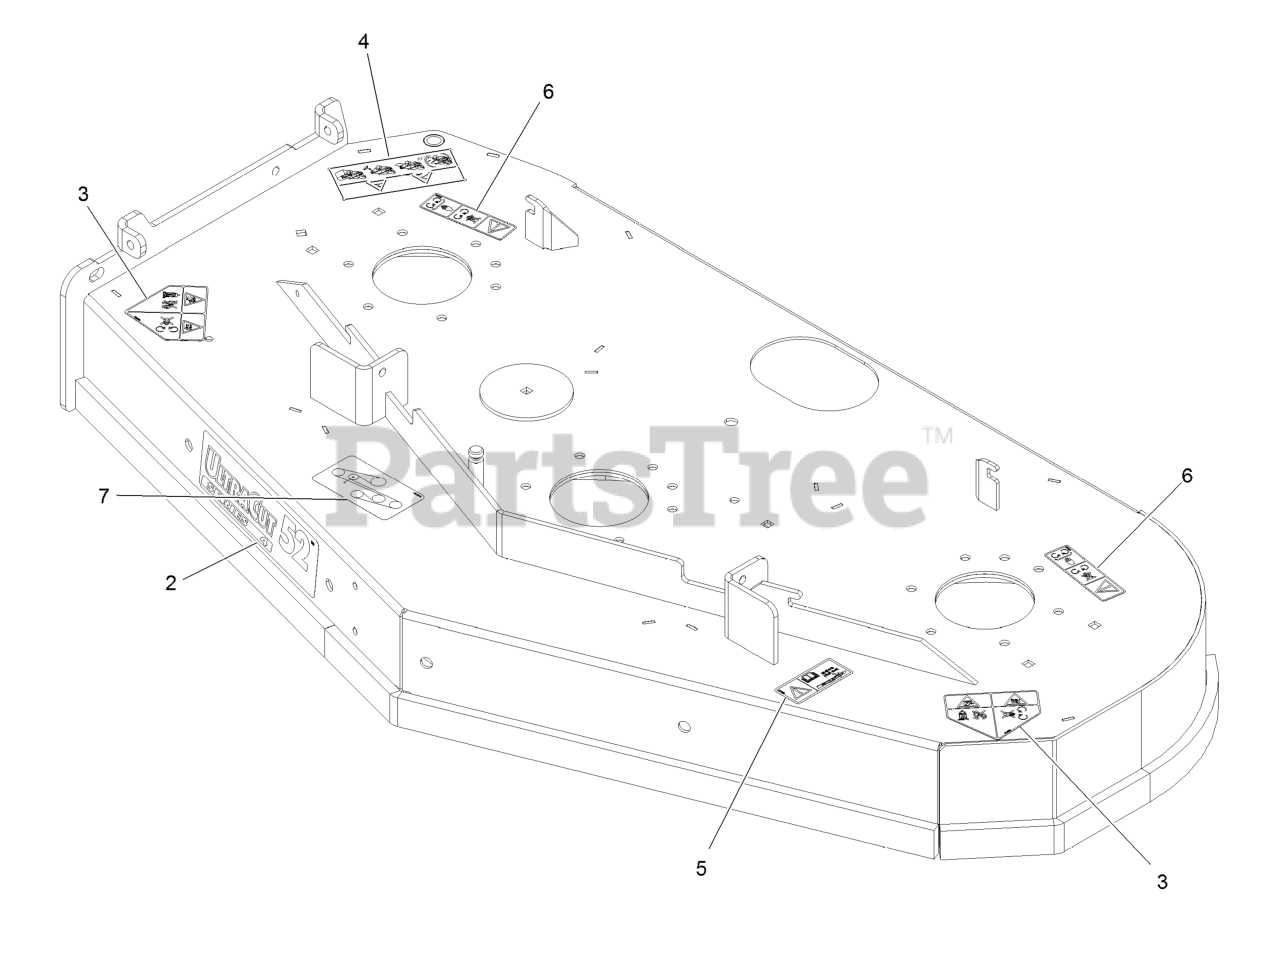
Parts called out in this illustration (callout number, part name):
2	DECAL,ULTRACUT 52 SERIES
3	DECAL-DANGER
4	DECAL-WARNING, BAGGER
5	DECAL-BOLT TORQUE
6	DECAL-COVER, MISSING
7	DECAL-BELT ROUTING
